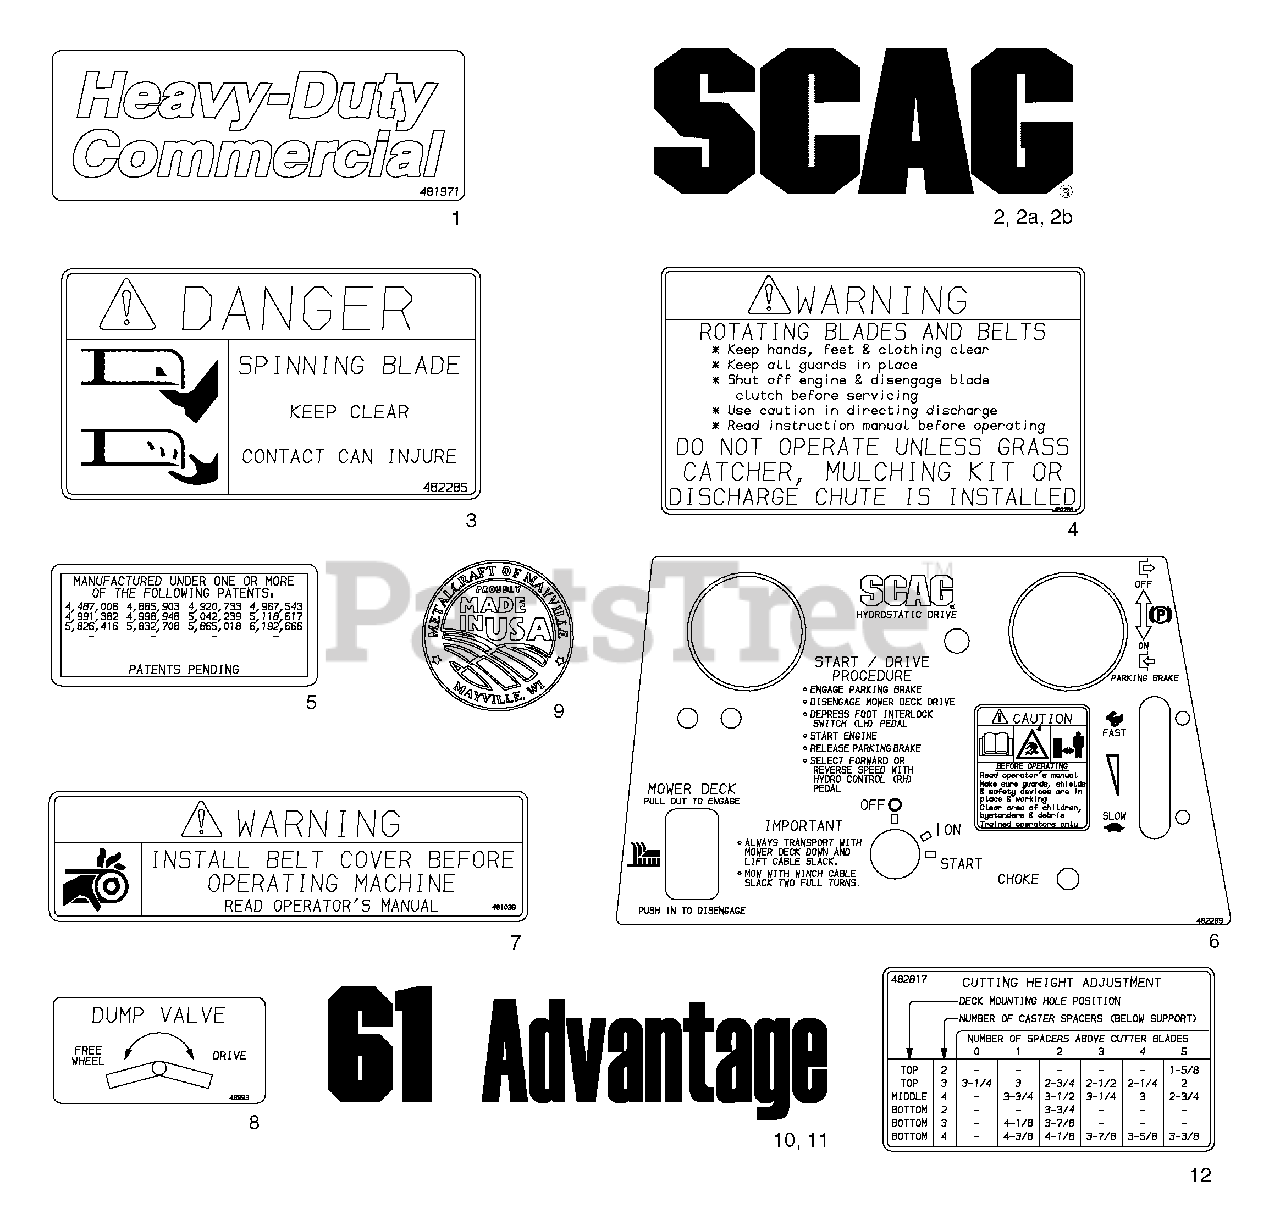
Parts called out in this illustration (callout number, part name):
1	Decal, Heavy Duty Commercial
2	Decal, Scag Logo ( Cutter Deck)
2A	Decal, Scag Logo (Battery Box Front)
2B	Decal, Scag Logo Seat Back
3	Decal, Danger-Spinning Blades
4	Decal, Warning-Rotating Blades
5	Decal, Patent
6	Decal, Instrument Panel
7	Decal, Warning-Belt Cover
8	Decal, Dump Valve
9	Decal, Metalcraft-Made In USA
10	Decal, 61 Advantage
11	Decal, 72 Advantage
12	Decal, Height of Cut
